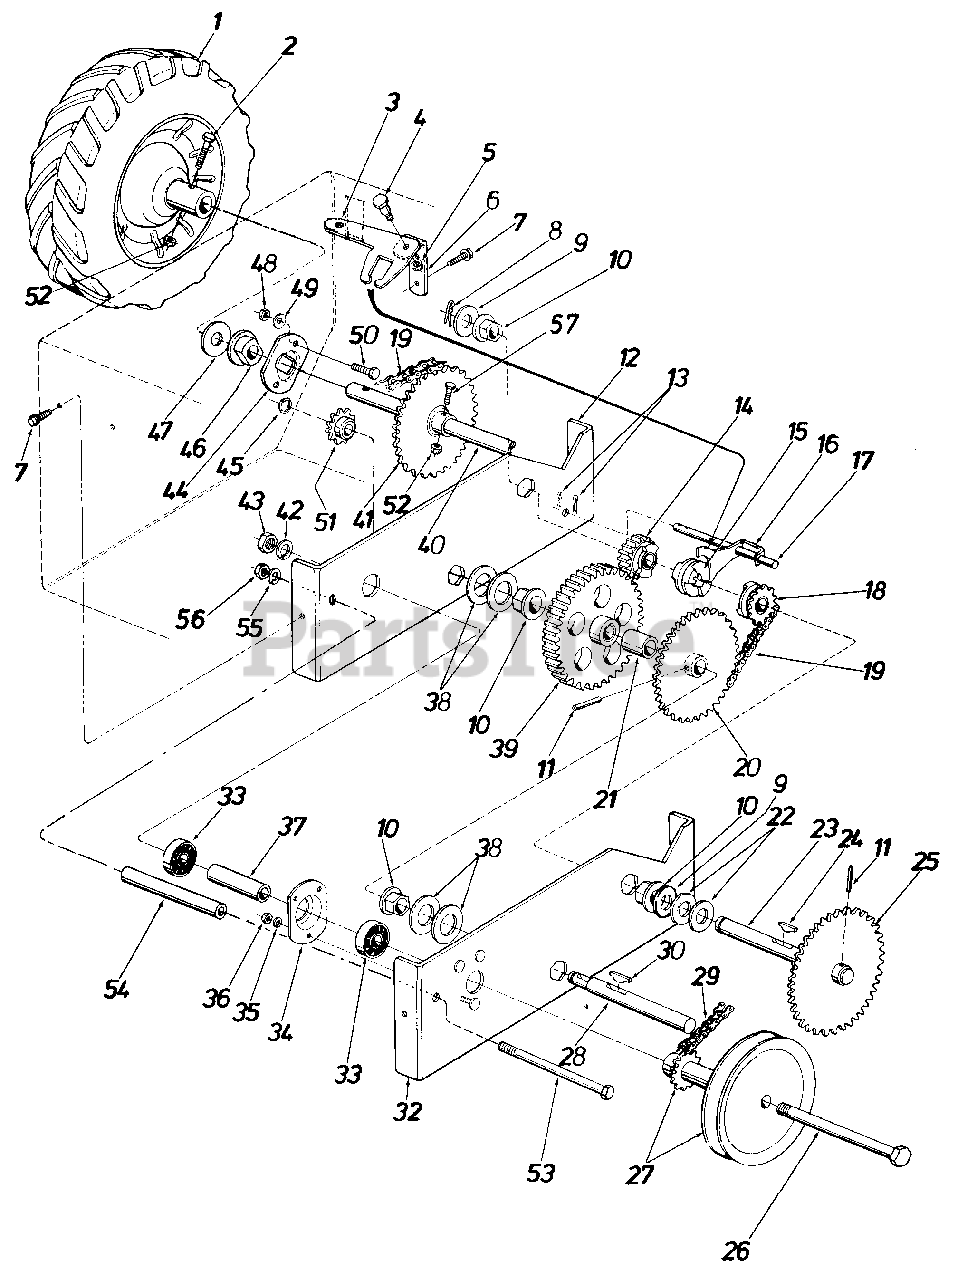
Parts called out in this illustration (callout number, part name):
1	Wheel Ass'y.Comp. 10 x 2.75-R.H.
2	Hex Bolt 5/16-24 x 1.75" Lg. H.T.
3	Shifting Bracket
4	Shld. Scr. .438" Dia. x .180 Lg.
5	Hex Ins. L-Nut 5/16-18 Thd.
6	Shifting Bracket Support
7	He Wash. Hd. Self-Tap Scr. 5/16-24 x .50
8	Coter Pin 3/32 Dia. x 1.00"
9	Fl-Wash. .64 I.D. x 1.25 O.D. x .060
10	Hex Flange Brg. .63 I.D.
11	H-Spring Pin Spiral 1/4" Dia. x 1.50 Lg.
12	Drive Housing Bracket- R.H.
13	Internal Coter Pin 3/8" Dia.
14	Spur Gear-21 Teeth
15	Clutch Collar
16	Shifting Yoke
18	Sprocket-10 Teeth
19	#41 Chain-1/2" Pitch x 33 Links
20	28 Teeth-Sprocket Hub Ass'y.
21	Spacer-.62 I.D. x .88 O.D. x 1.030
22	Fl-Wash. .64 I.D. x 1.25 O.D. x .100
23	Shifting Shaft
24	Hi-Pro Key 3/16 x 3/4" Dia. x 1.062
25	32 Teeth Sprocket Hub Assly.
26	Hex Scr. 1/2-20 x 5.50" Lg.
27	5.25" O.D. Pulley with 9 Teeth Sprocket
28	Shaft
29	#41 Chain 1/2 Pitch x 47 Links
30	Hi-Pro Key-3/16 x 3/4" Dia.
32	Drive Housing Bracket Ass'y. L.H .
33	Ball Bearing .500 I.D. x 1.38 O.D. x .438
34	Bearing Housing
35	L-Wash. 1/4 Scr.
36	Hex Nut 1/4-20 Thd.
37	Spacer-.52 I.D. x .62 O.D. x 2.69
38	Fl-Wash. 1.06 I.D. x 1.75 O.D. x .100
39	Spur Gear-62 Teeth
40	Wheel Axle
41	28 Teeth-Sprocket Hub Ass'y.
42	L-Wash. 1/2" I.D.
43	Hex Ins. Jam L-Nut 1/2-20 Thd.
44	Bearing Plate
45	External C-Ring
46	Flange Bearing w/Flats .753 I.D.
47	Fl-Wash. .81 I.D. x 1.25 O.D. x .060
48	Hex Nut 5/16-18 Thd.
49	Bell-Wash. 5/16" I.D.
50	Carriage Bolt 5/16-18 x .75"
51	8 Teeth Sprocket #41 Chain
52	Hex Jam L-Nut 5/16-24 Thd.
53	Hex Bolt 5/16-18 x 4.0" Lg.
54	Spacer 3.25" Lg.
55	L-Wash. 5/16" I.D.
56	Hex Nut 5/16-18 Thd.
57	Hex Bolt 5/16-24 x 1.5" Lg.
